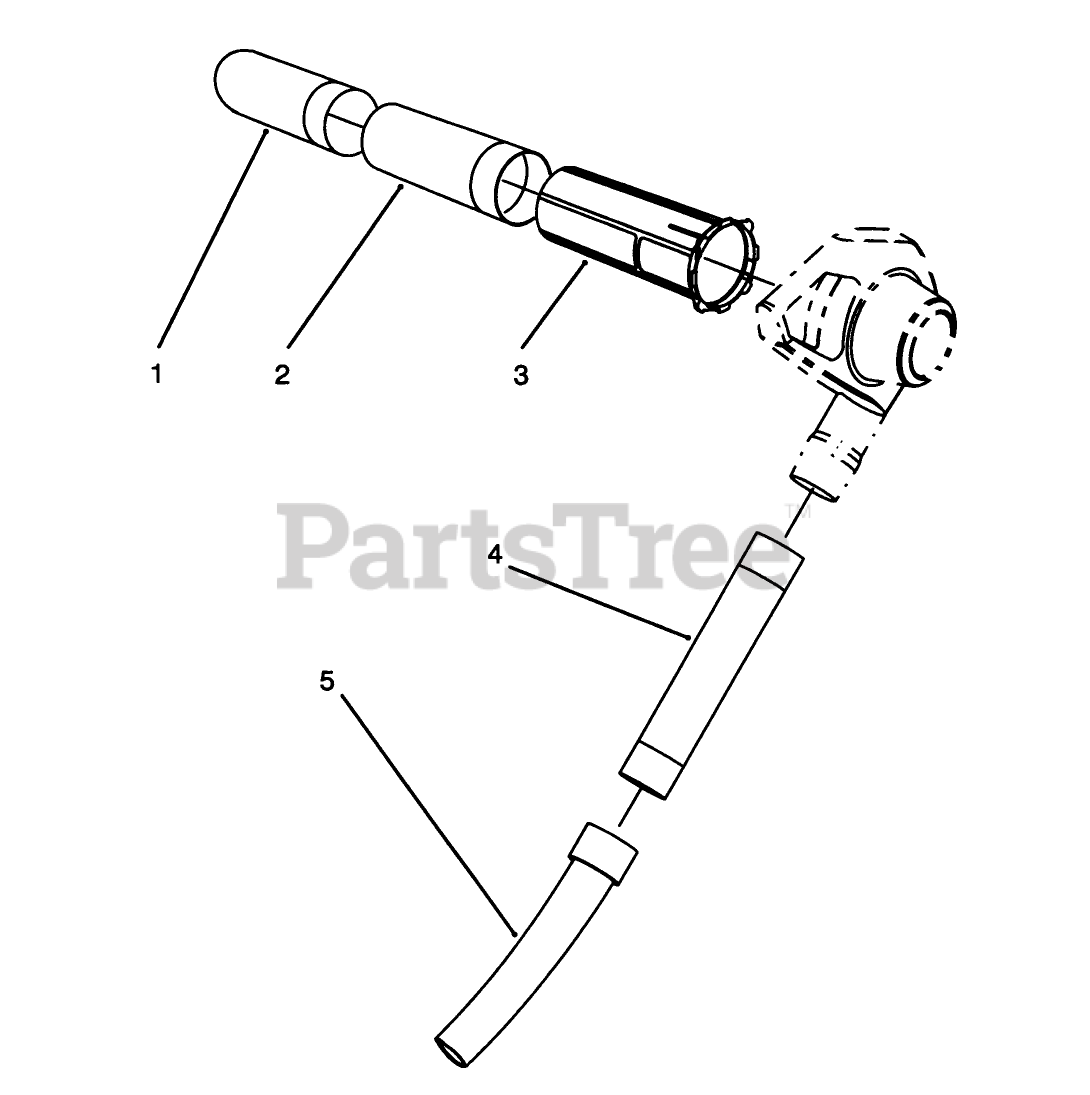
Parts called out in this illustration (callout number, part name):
1	LOWER VAC TUBE
2	MIDDLE VAC TUBE
3	UPPER VAC TUBE
4	BLOWER TUBE
5	MID BL-DISCHARGE TUBE
